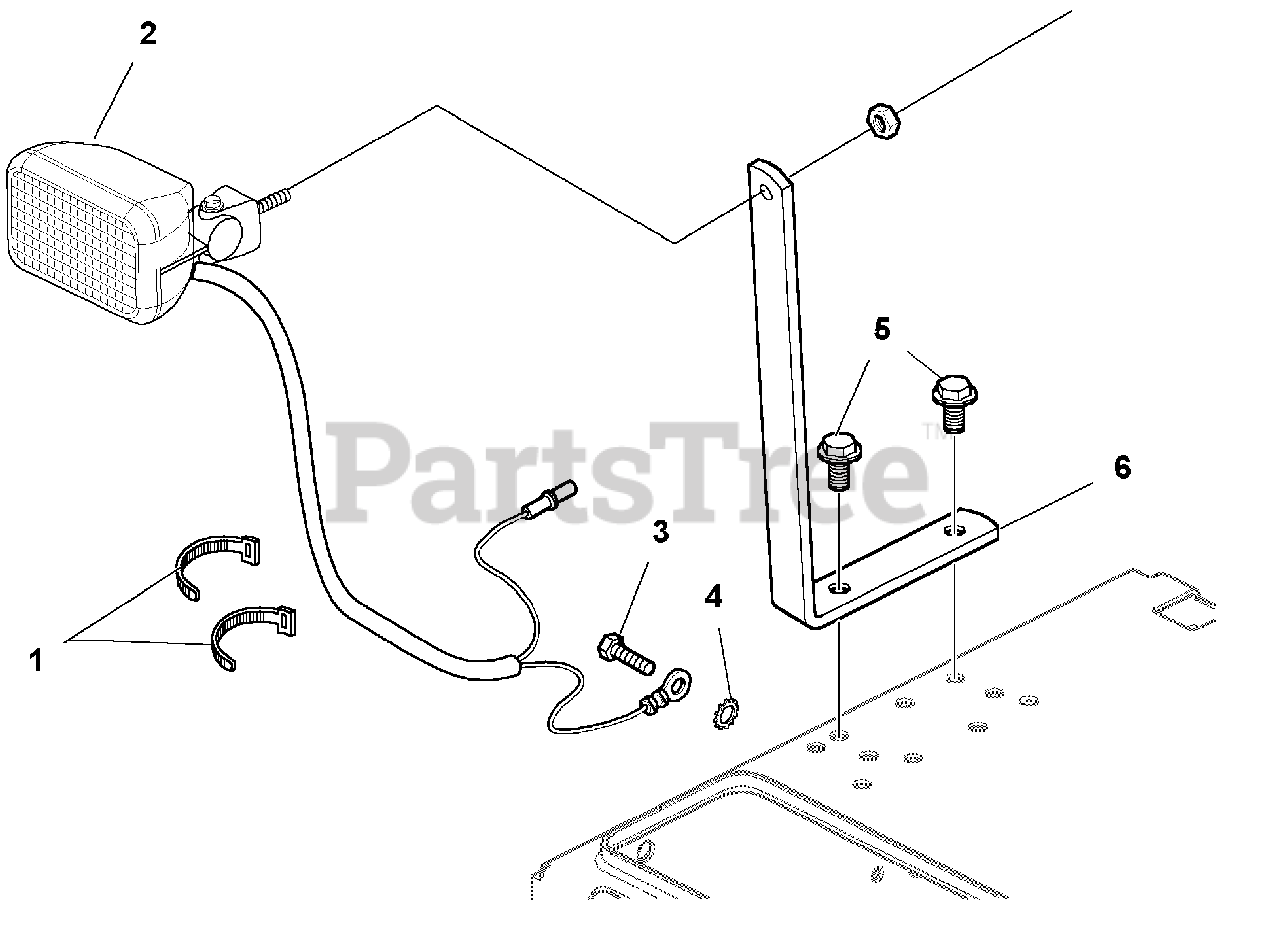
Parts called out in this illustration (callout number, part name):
2	LIGHT & COVER ASSEMBLY
3	CARRIAGE BOLT, 5/16-18 x 1-3/4
4	LOCKNUT, Nylon, 5/16-18
5	CAPSCREW, Hex Hd. Taptite, 3/8-16 x 3/4
7	CARRIAGE BOLT, 5/16-18 x 1-3/4
7	CAPSCREW, Hex Hd., 1/4-20 x 1/2
8	LOCKNUT, Nylon, 5/16-18
8	LOCK WASHER, External Tooth, 1/4
9	CAPSCREW, HEX HD., 5/16-18 x 1
10	WASHER
11	LOCK WASHER, Internal Tooth
